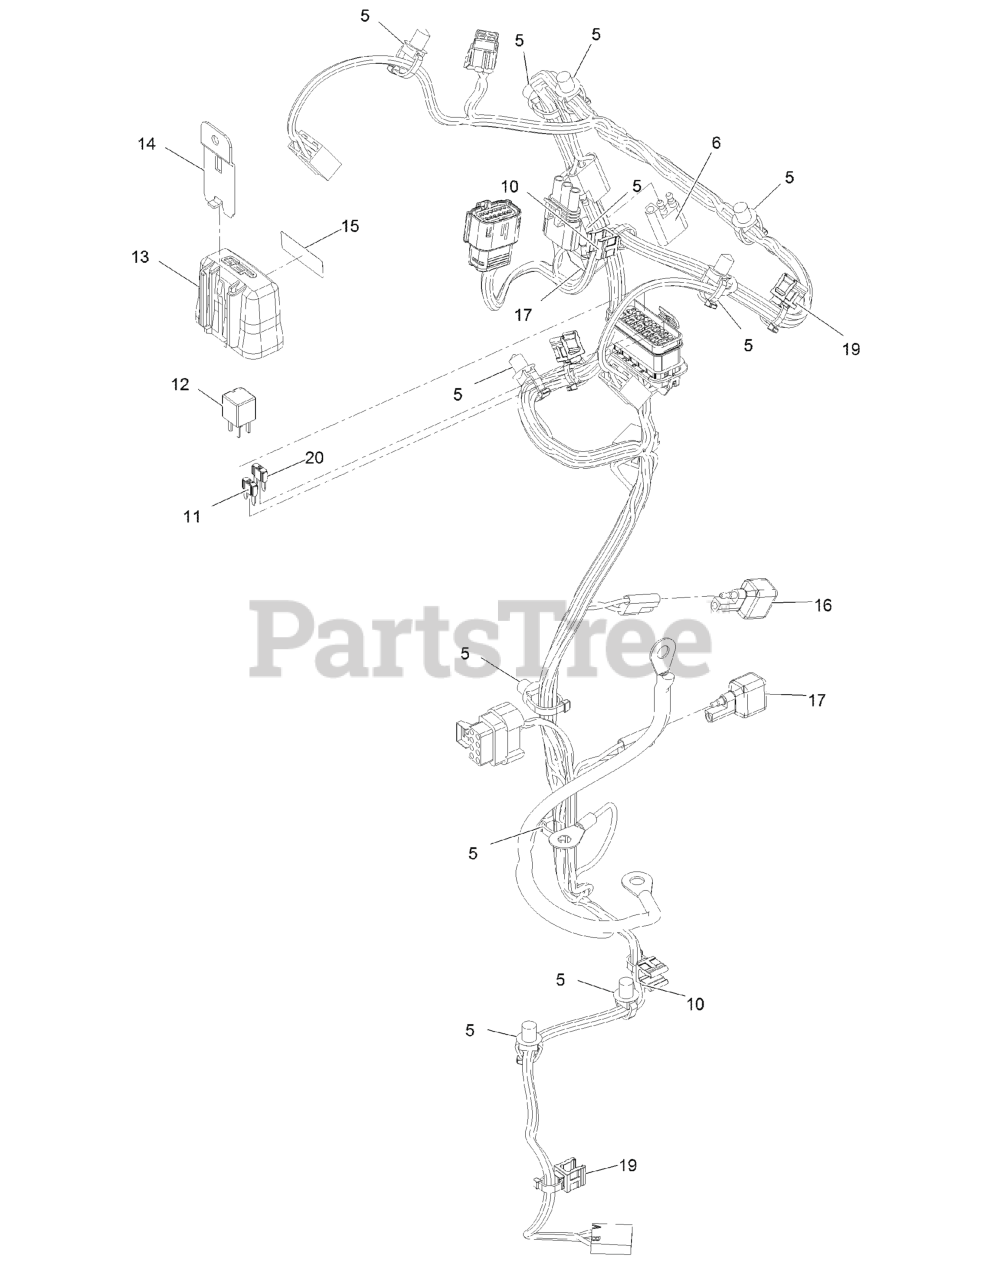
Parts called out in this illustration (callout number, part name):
5	CLIP-TIE
6	Cap-Plug
10	Clip-Edge
11	FUSE-MINI BLADE, 20 AMP
12	RELAY-MICRO
13	COVER-BLOCK, FUSE
14	CLIP-MOUNTING
15	DECAL-FUSE
19	Clip-Edge W/Tie, Perpendicular
20	FUSE-MINI BLADE, 15 AMP
